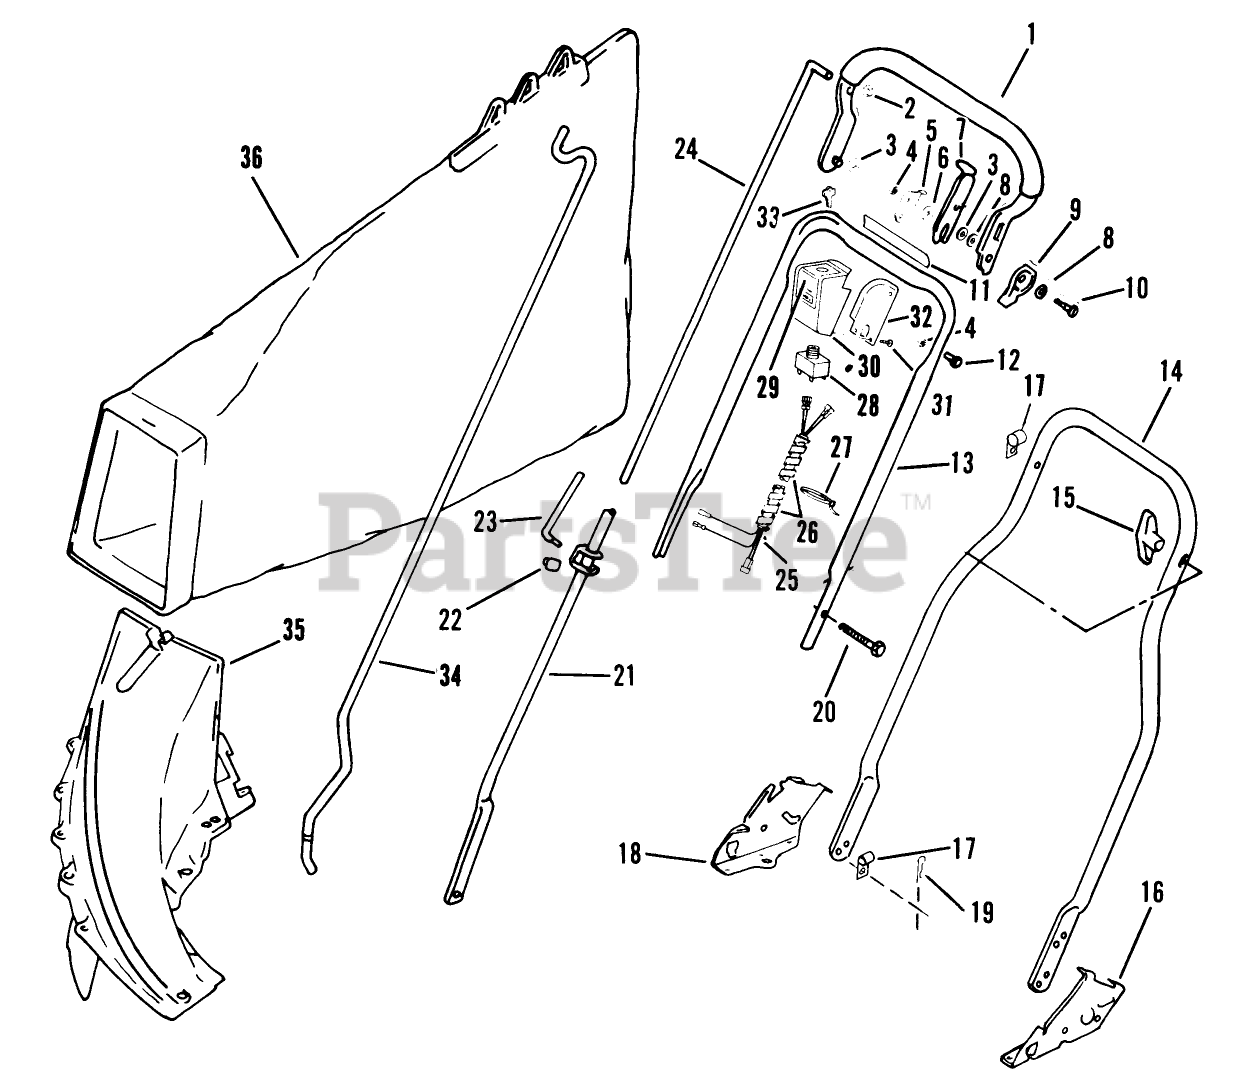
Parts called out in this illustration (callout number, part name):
3	WASHER M
4	LOCKNUT E
5	HANDLE STOP
6	WASHER
7	LEVER LOCKOUT
10	BOLT PIONEER
12	SCREW-HANDLE STOP
13	HANDLE
15	NUT-WING
18	HANDLE BRACKET
19	HAIR PIN
24	ROD CONTROL
30	HOUSING SWITCH
34	ROD GRASSBAG
36	89802 LB WHOLE GOODS
